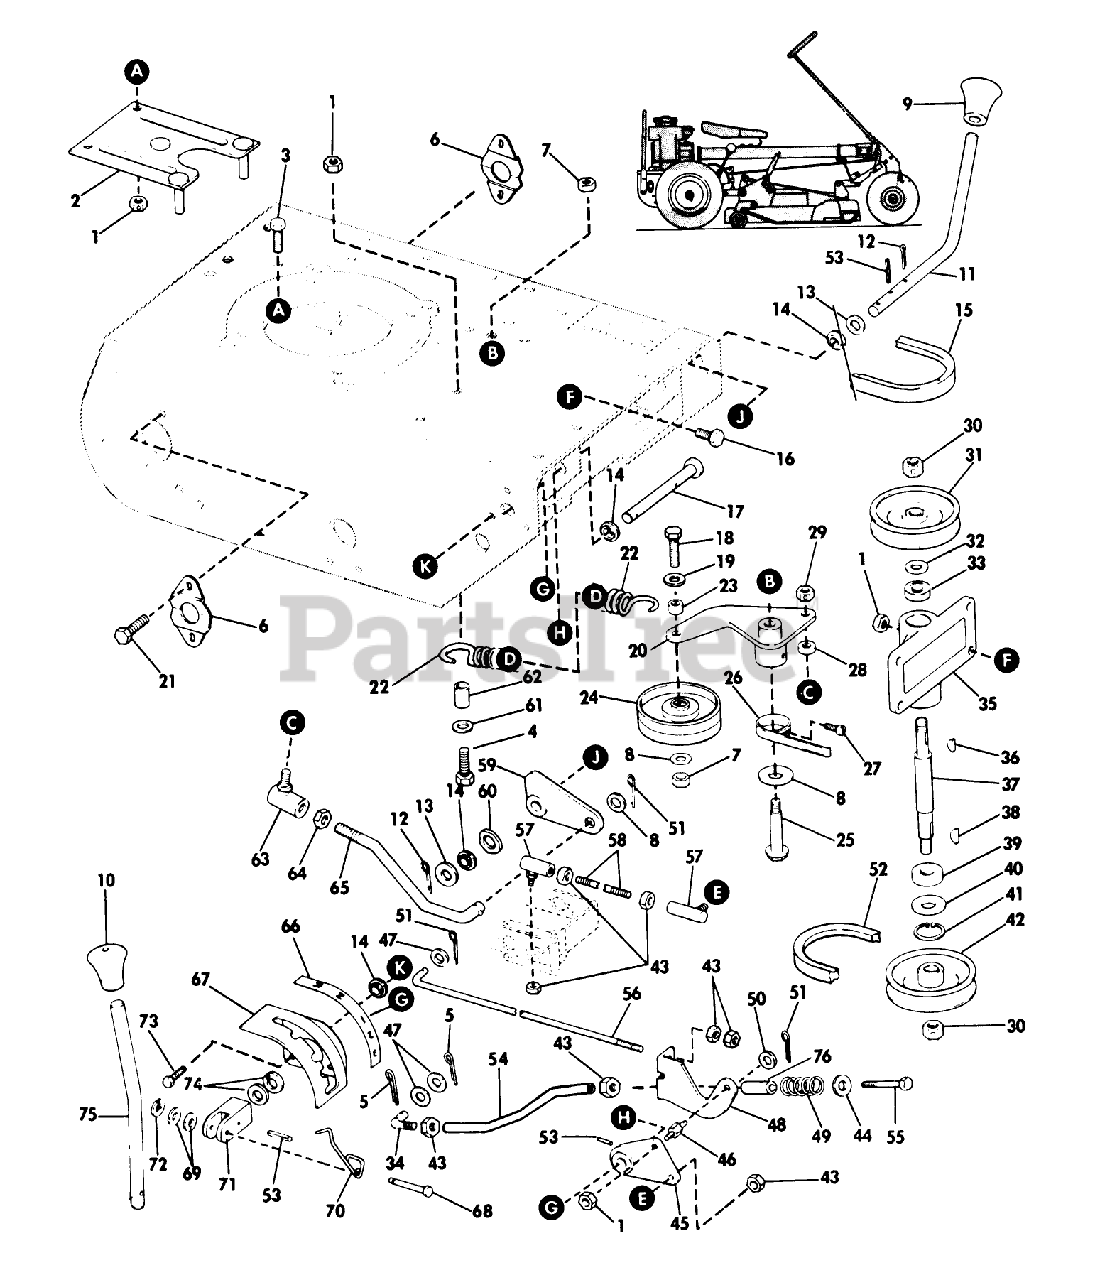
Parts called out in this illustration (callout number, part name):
7	LOCKNUT
12	Cotter Pin
43	STOP NUT
